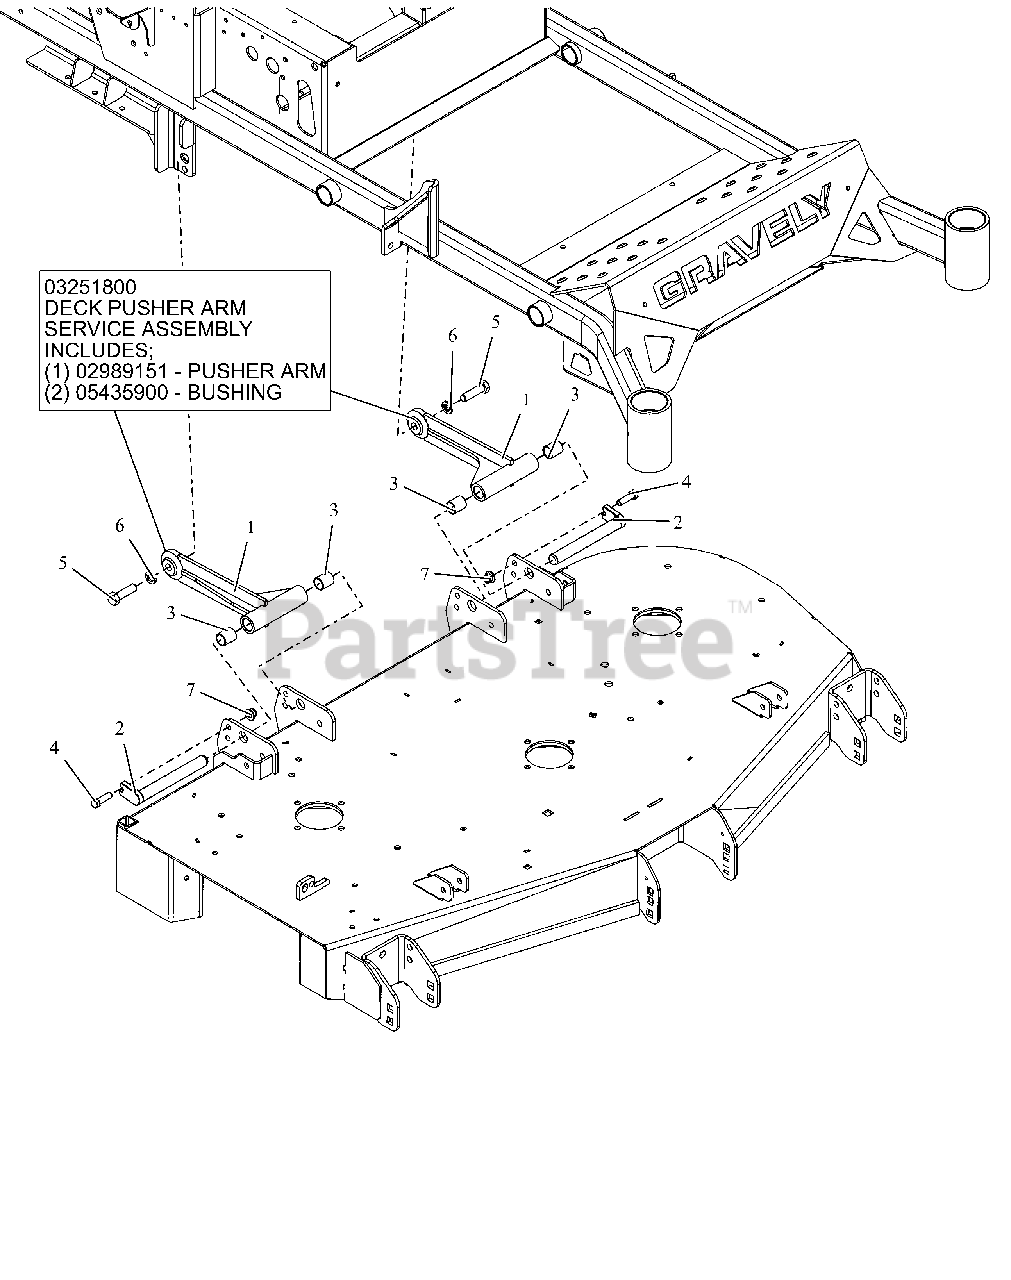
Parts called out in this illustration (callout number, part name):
1	DECK PUSHER ARM WMT - BLACK
1	DECK PUSHER ARM ASSEMBLY
2	PIN, MOWER MTG
3	BRG, .750 X .875 X 1.000
4	@BLT-HEX .38-16X1.25 GR5 YWZC
5	BLT-HEX .50-13X1.75 GR5EP80 YZ
6	@WSHR-LK .50X.125 REG YWZC
7	@NUT-LK-NYL-FLG .38-16 YWZC
